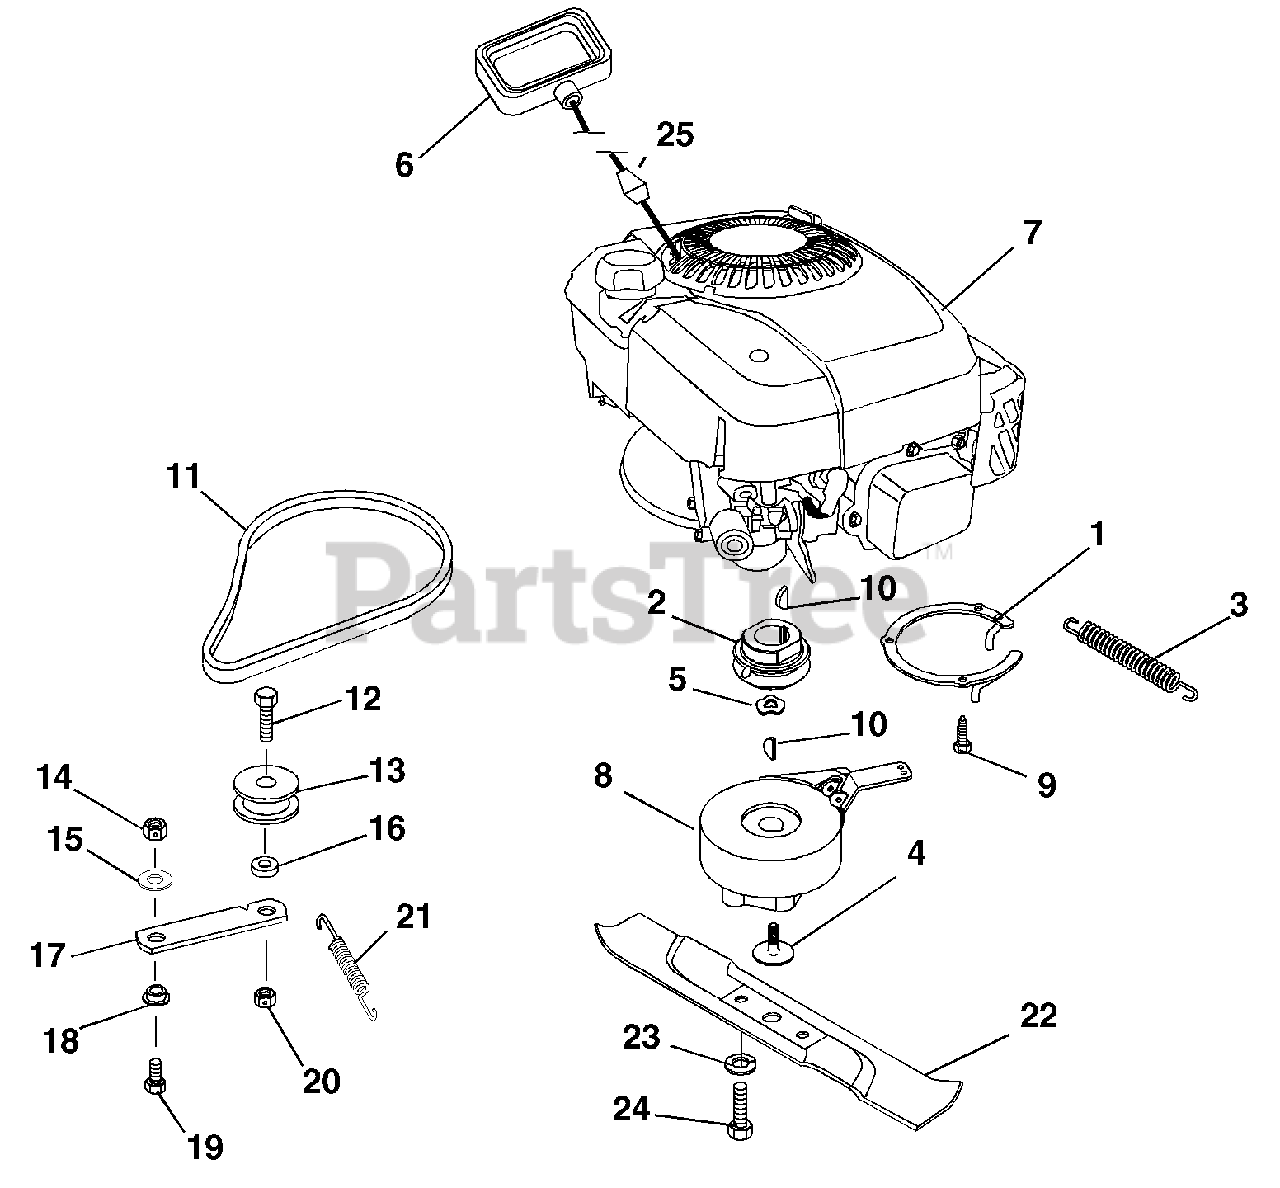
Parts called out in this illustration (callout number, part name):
1	BRACKET - SPRING RETAINER
2	PULLEY - BBC
3	SG-TENS .1278X.735X4.71 WLD40
4	SCR-SKH-SPECIAL .375-24X1.50
5	WASHER-WAVE .885X1.311X.125
6	HANDLE, RECOIL START
7	ENGINE, 6.75HP B&S INTEK - BBC
8	BLADE BRAKE CLUTCH
9	@SCR-TAP .38-16X1.00 HWH TR YZ
10	KEY-WDRF .156X.625X.25 SAE 6
11	V-BELT, 3L-COGGED
12	@BLT-HEX .44-14X1.50 GR5 YWZC
13	IDLER-FLAT 1.75 X .47
14	@NUT-LK-CTR .31-18 YWZC
15	WSHR-FL-STL .323X.625X.062 YWZ
16	BSHG-SLV .469 X .750 X .430
17	IDLER ARM
18	BSHG-FLG .325X.501X.250X1.120
19	@BLT-HEX .31-18X.75 GR5 YWZC
20	@NUT-LK-CTR .44-14 YWZC
21	SG-TENS .043X.44X3.31 WLD 5.8
22	21" MULCH BLADE - BBC
23	@WSHR-LK .44X.109 REG YWZC
24	BLT-HEX M10 X 1.5X25 YWZC
25	ROPE STOP
